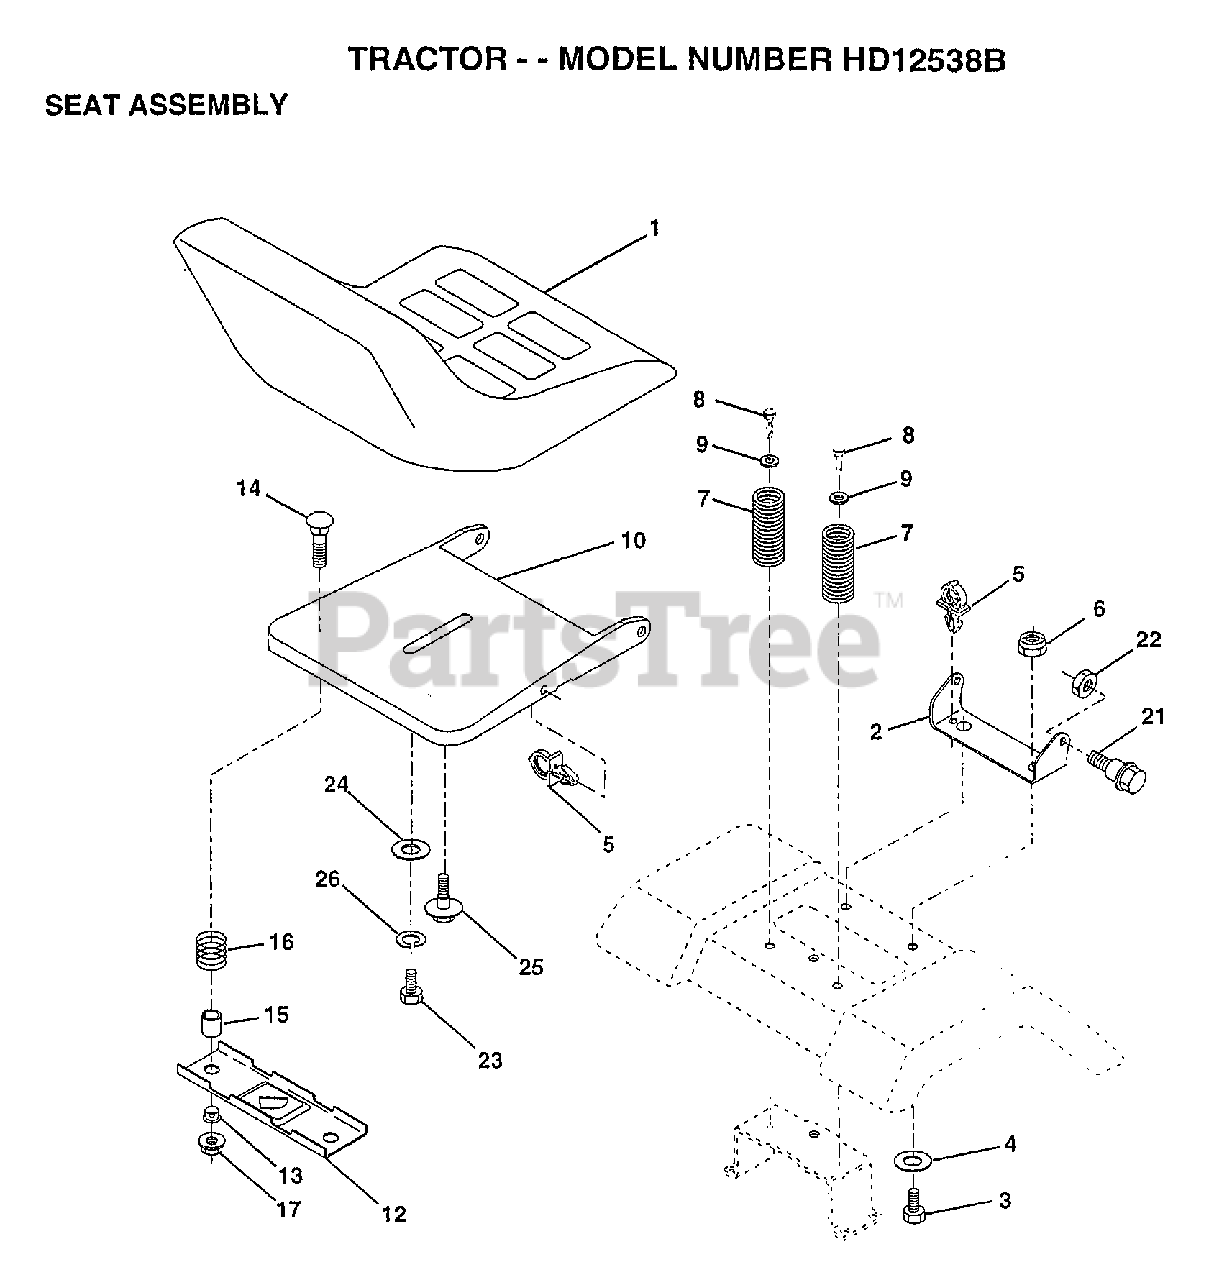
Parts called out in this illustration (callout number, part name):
2	BRACKET PVT SEAT
3	BOLT
4	WASHER PM
5	CLIP.PUSH-IN.HING
6	NUT
7	SPRING COMPRESSIO
8	SCREW GTV
9	WASHER
10	PAN-SEAT
12	BRKT SWITCH
13	BUSHING
15	SPLIT SPACER
16	SPRING
21	"BOLT,SHOULDER"
22	NUT
23	BOLT
24	WASHER
25	"BOLT,SHOULDER"
26	LOCKWASHER
